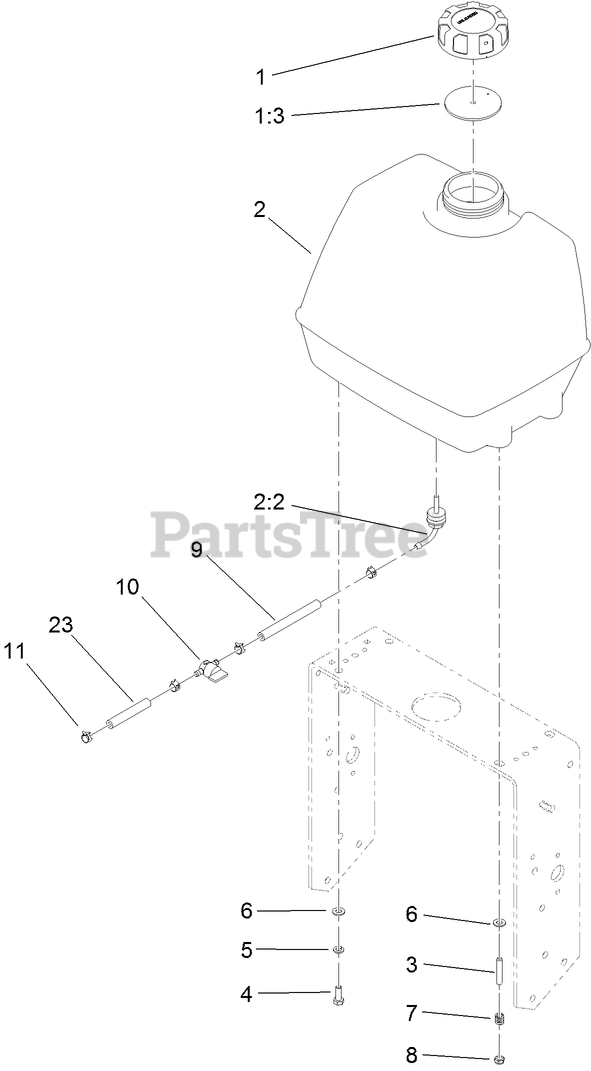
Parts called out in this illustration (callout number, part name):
1	GAS CAP ASM
1:3	GASKET-CAP, GAS
2	FUEL TANK ASM
2:2	FITTING-FUEL, BULKHEAD
3	STUD-THREADED
4	SCREW-HH
5	WASHER-LOCK
6	WASHER-PLAIN
7	SPRING-TANK, FUEL
8	NUT-LOCK, NI
9	HOSE-FUEL
10	VALVE-FUEL
11	CLAMP-HOSE
23	HOSE-FUEL
